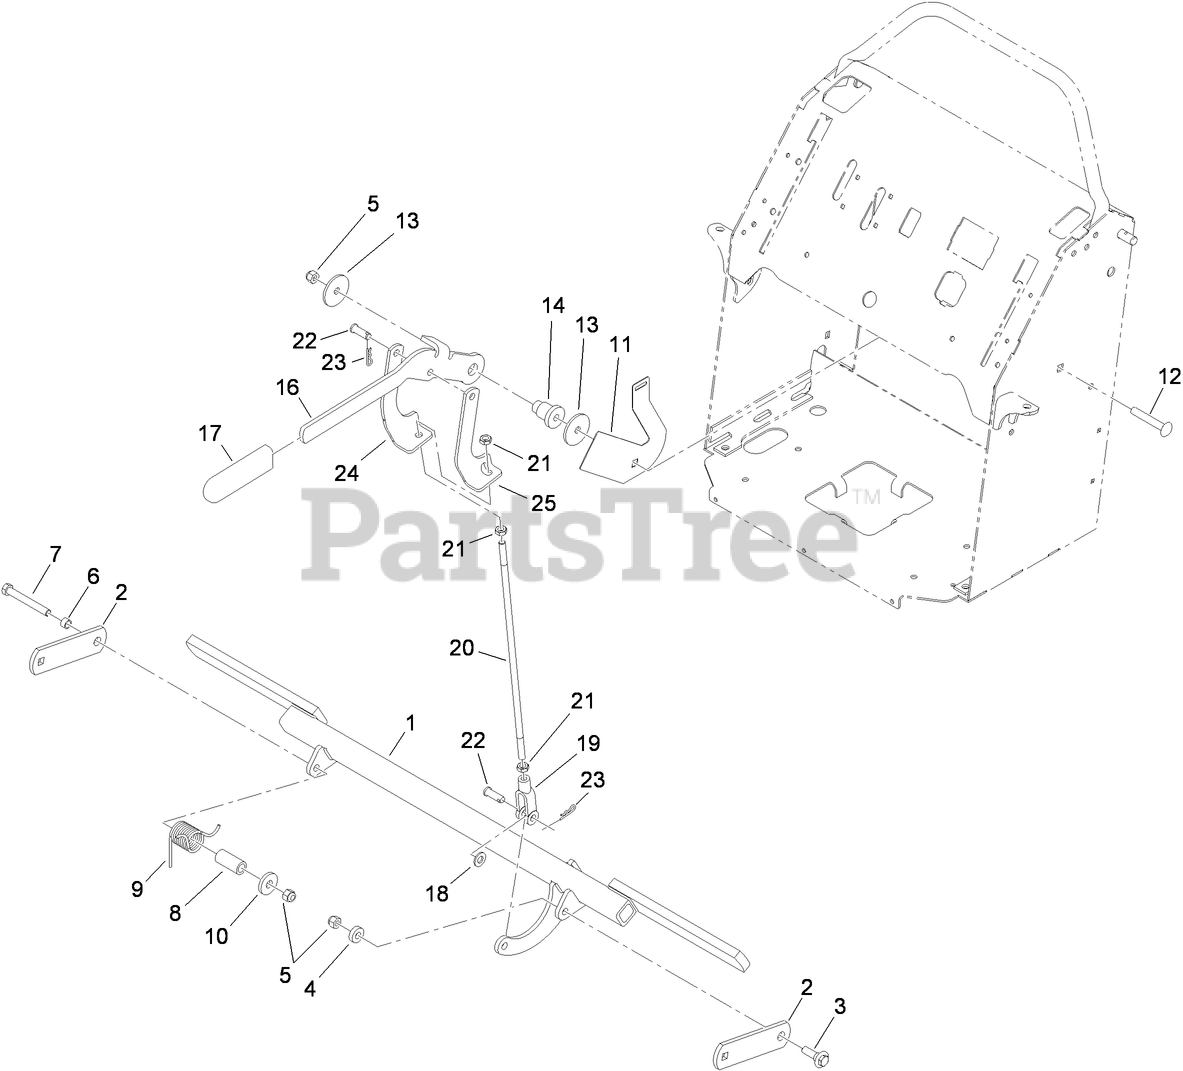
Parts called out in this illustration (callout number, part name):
1	BRAKE ASM
2	SUPPORT-BRAKE
3	SCREW-SHOULDER, HWH
4	SPACER
5	NUT-LOCK, NI
6	SPACER
7	SCREW-HH
8	SPACER
9	SPRING-TORSION
10	WASHER
11	PLATE-SWITCH, BRAKE
12	SCREW-CARR
13	WASHER-REBOUND
14	MOUNT-PULLEY
16	LEVER-BRAKE
17	GRIP-LEVER
18	WASHER-FLAT
19	YOKE-LINKAGE, BRAKE
20	ROD-BRAKE
21	NUT-HJ
22	PIN-CLEVIS
23	PIN-COTTER
24	ARM-BRAKE, BOTTOM
25	ARM-BRAKE, TOP
